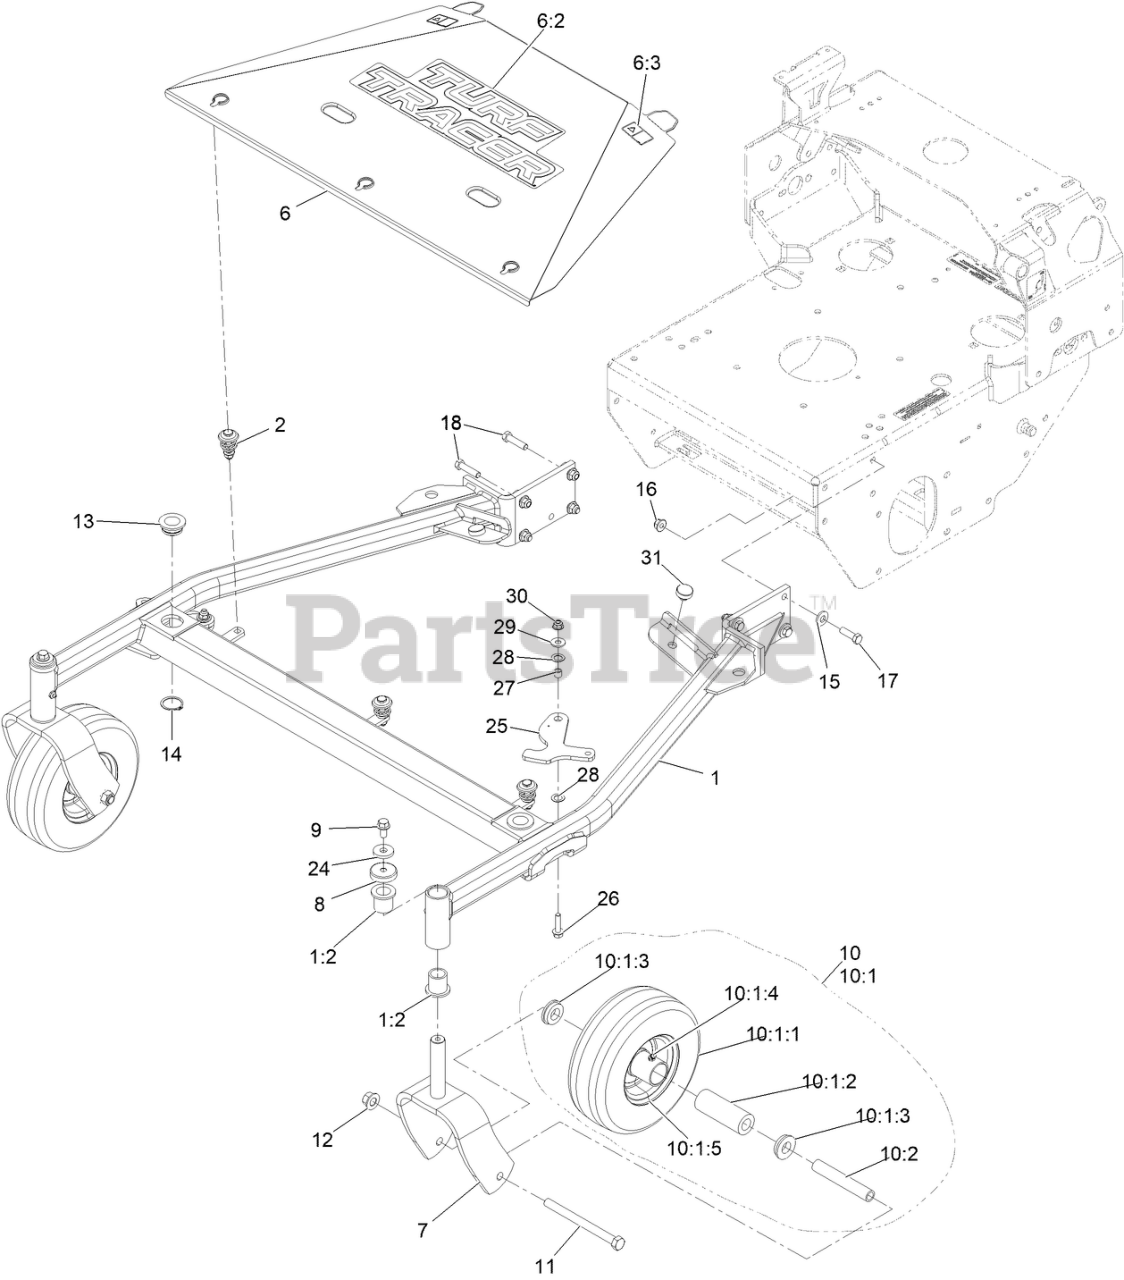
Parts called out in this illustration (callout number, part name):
1	ASM-52" Tts Front Frame
1:2	BEARING-FLANGED
2	HOOD RETAINER, TURF TRACER
6	ASM-52" Tts Center Shield
6:2	DECAL-TURF TRACER
6:3	DECAL-WARNING
7	FORK, CASTER
8	CAP, DUST
9	SCREW-HHF
10	KIT, SP CASTER WHEEL REPLACEMENT
10:1	Wheel And Tire ASM
10:1:1	Tire
10:1:2	BEARING
10:1:3	BUSHING
10:1:4	FITTING-GREASE
10:1:5	Wheel
11	SCREW-HH
12	Nut-Lock 1/2-13
13	BUSHING-DECK
14	RING-RETAINING
15	WASHER-BELLEVILLE
16	NUT-HF, NI
17	SCREW-HH
18	SCREW-HH
25	LATCH, DECK HEIGHT
26	Screw-HHF
27	Spacer-Grommet
28	WASHER-CONICAL
29	WASHER-FLAT
30	NUT-HF, NI
31	BUMPER-RUBBER
